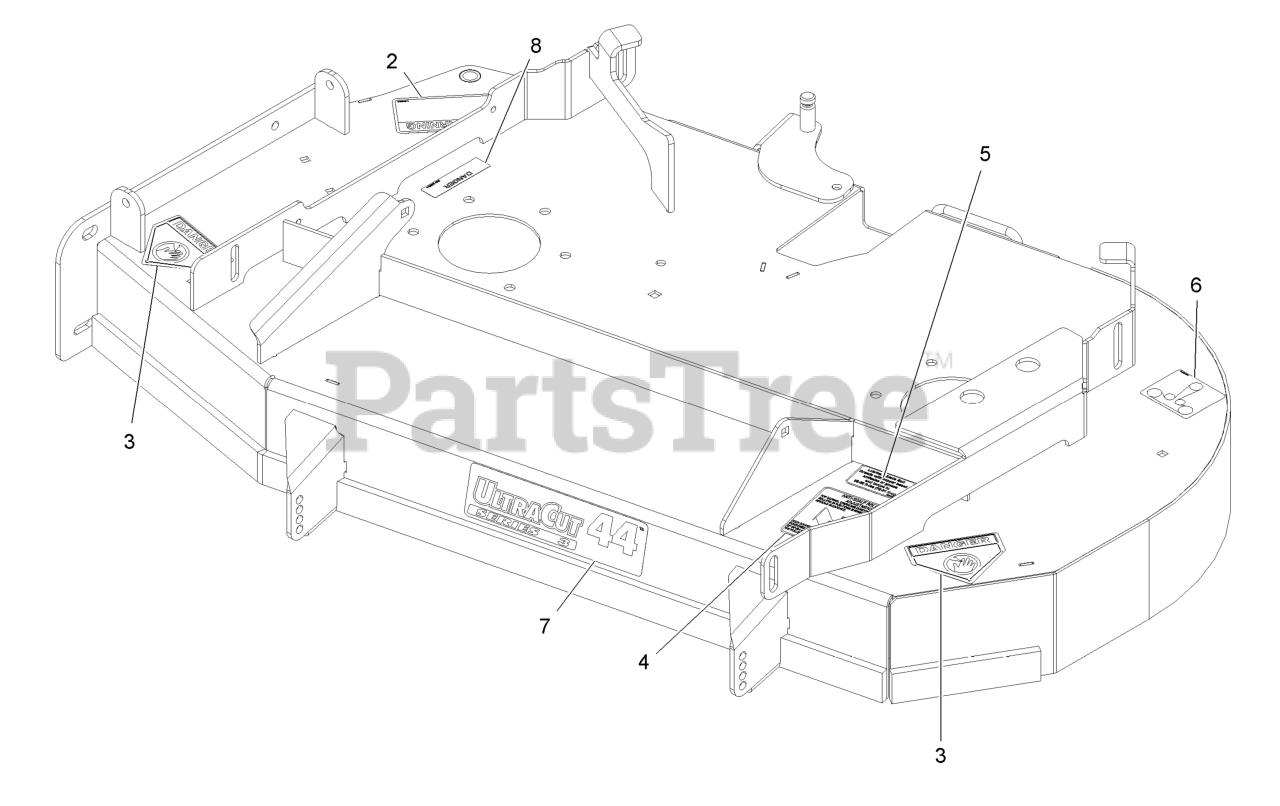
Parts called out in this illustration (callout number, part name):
2	DECAL-WARNING, DISCHARGE
3	DECAL-DANGER
4	DECAL,ANTISCALP
5	DECAL,BOLT TORQUE
6	DECAL-ROUTING, BELT
7	DECAL-ULTRACUT 44 SERIES
8	DECAL-COVER, MISSING
